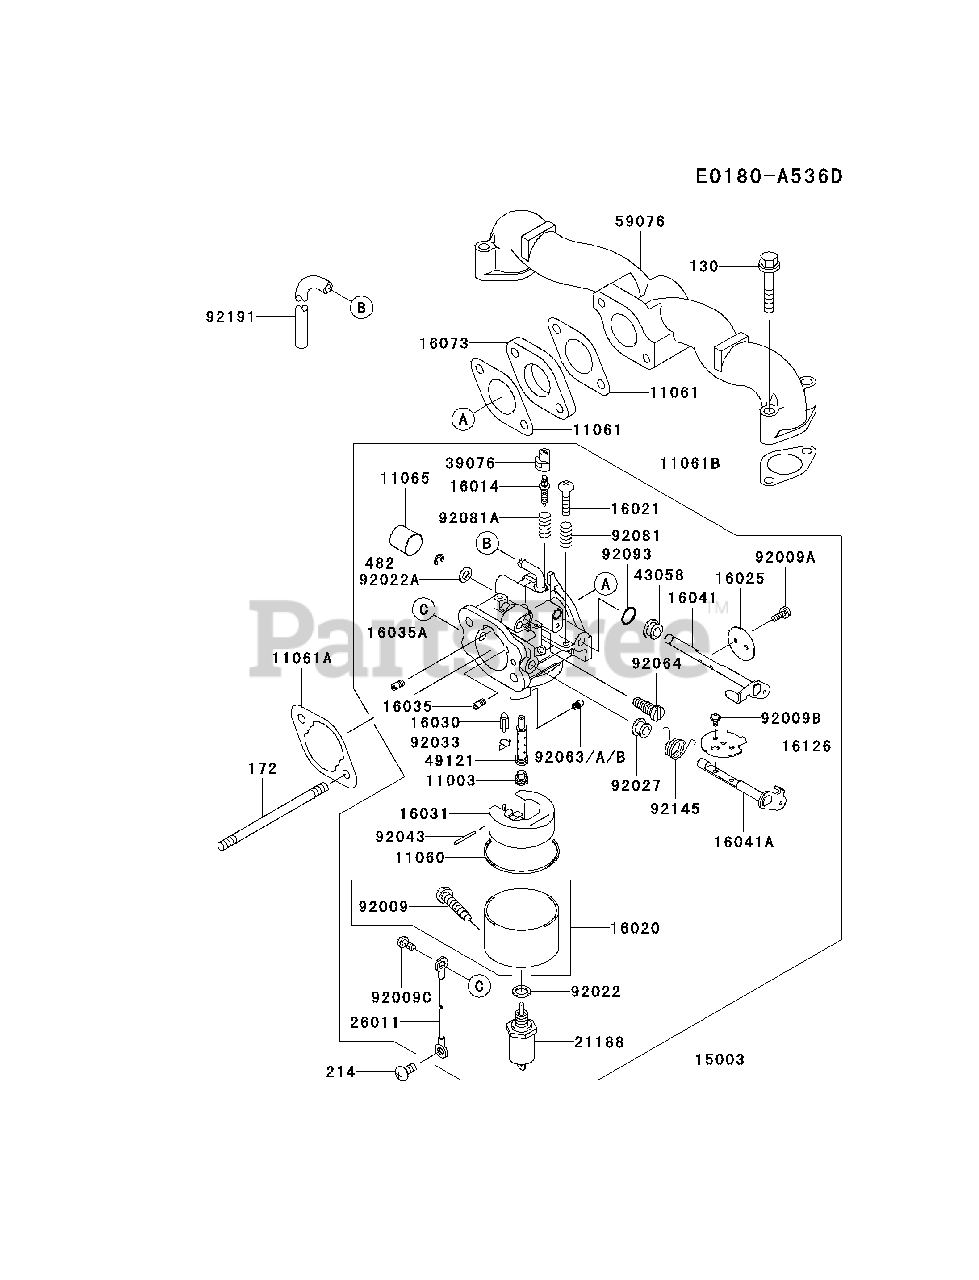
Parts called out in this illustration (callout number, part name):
130	BOLT-FLANGED
172	BOLT-STUD
214	SCREW-PAN+-
482	CIRCLIP-TYPE-E
92191	TUBE,4.76X7.94X225
